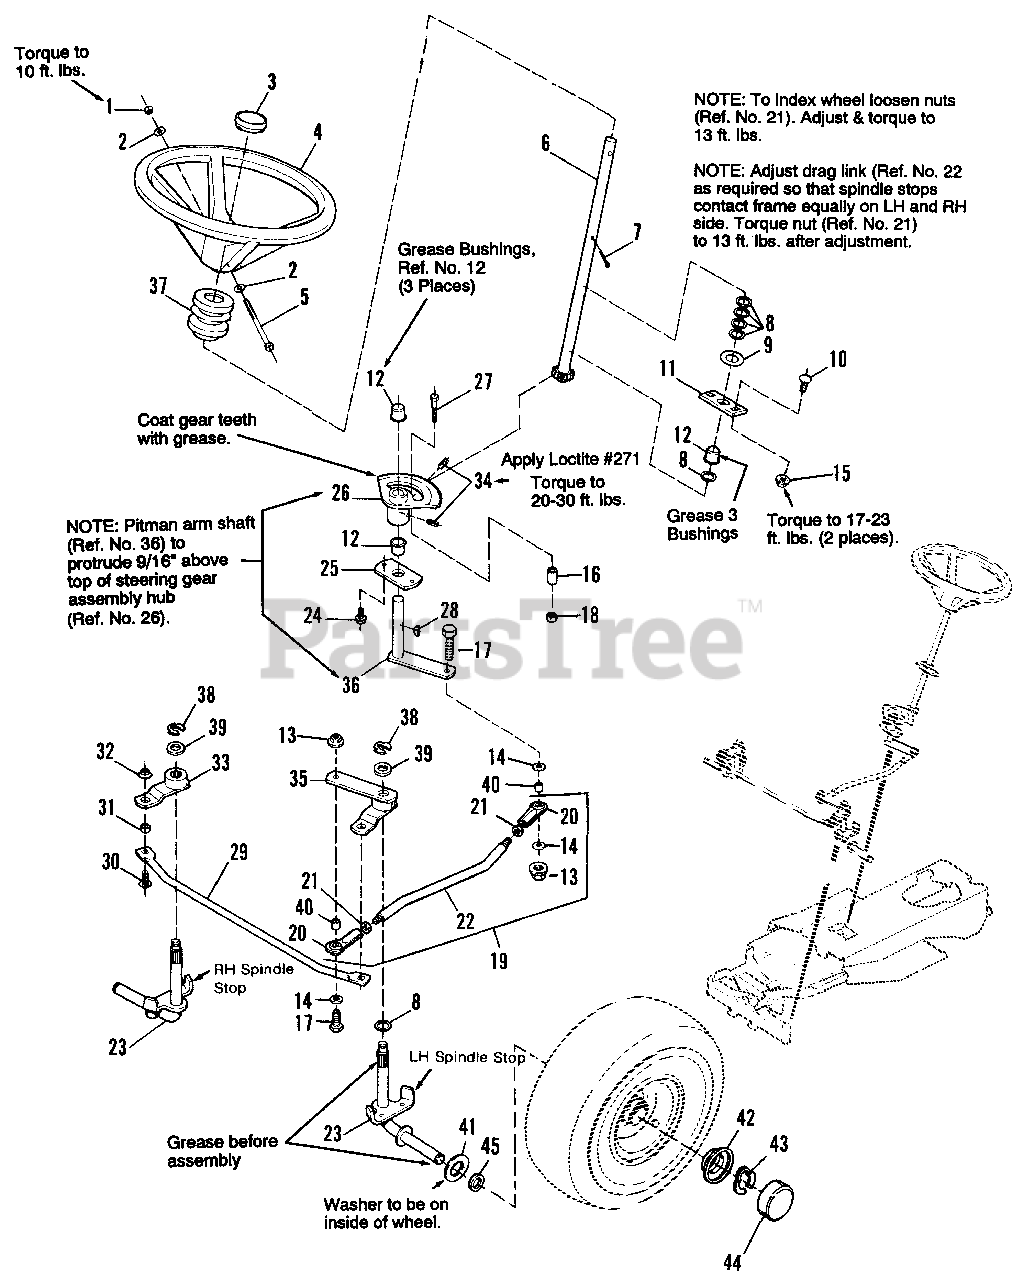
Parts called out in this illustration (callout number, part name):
1	NUT, Hex, Lock, 5/16-18
2	WASHER, Steering Wheel
3	CAP, Steering Wheel
4	STEERING WHEEL
5	CAPSCREW, 5/16-18 x 3-1/2
6	SHAFT ASSY., Steering
8	WASHER, Plain, 49/64
9	WASHER, Plain
10	CARRIAGE BOLT, 3/8-16 x 1
11	PLATE, Mounting, Steering
12	BUSHING, Nylon
13	NUT, Hex, Flange, 3/8-16
14	WASHER
15	NUT, Hex, Flange, Whizlock, 3/8-16
16	SPACER, Stop
17	CAPSCREW, Hex Hd., 3/8-16 x 1-1/2
18	NUT, Hex, Esna Lock, 5/16-18
19	DRAG LINK ASSY., (Incl. Ref. Nos. 14, 13, 17, 20, 21 & 22)
20	BALL JOINT, Flat
21	JAM NUT, Hex, 1/2-20
23	SPINDLE ASSY., Splined
24	SCREW, Taptite, 5/16-18 x 1
25	SECTOR MOUNTING PLATE
26	GEAR ASSY., Steering
27	CAPSCREW, Hex, 5/16-18 x 1-1/2
28	KEY, Hi Pro
30	CARRIAGE BOLT, 3/8-16 x 1
32	NUT, Hex, Lock, Flange, 3/8-16
33	ARM ASSY., Steering, R.H., Splined
34	SETSCREW, Sq. Hd., 5/16-18 x 1/2
35	STEERING ARM ASSY., L.H., Splined
36	PITMAN ARM ASSY.
37	TUBE, Steering
38	KLIP RING, 5/8
41	WASHER
42	RETAINER, Hubcap
43	RETAINING RING
45	WASHER, Special (Hydro models only)
